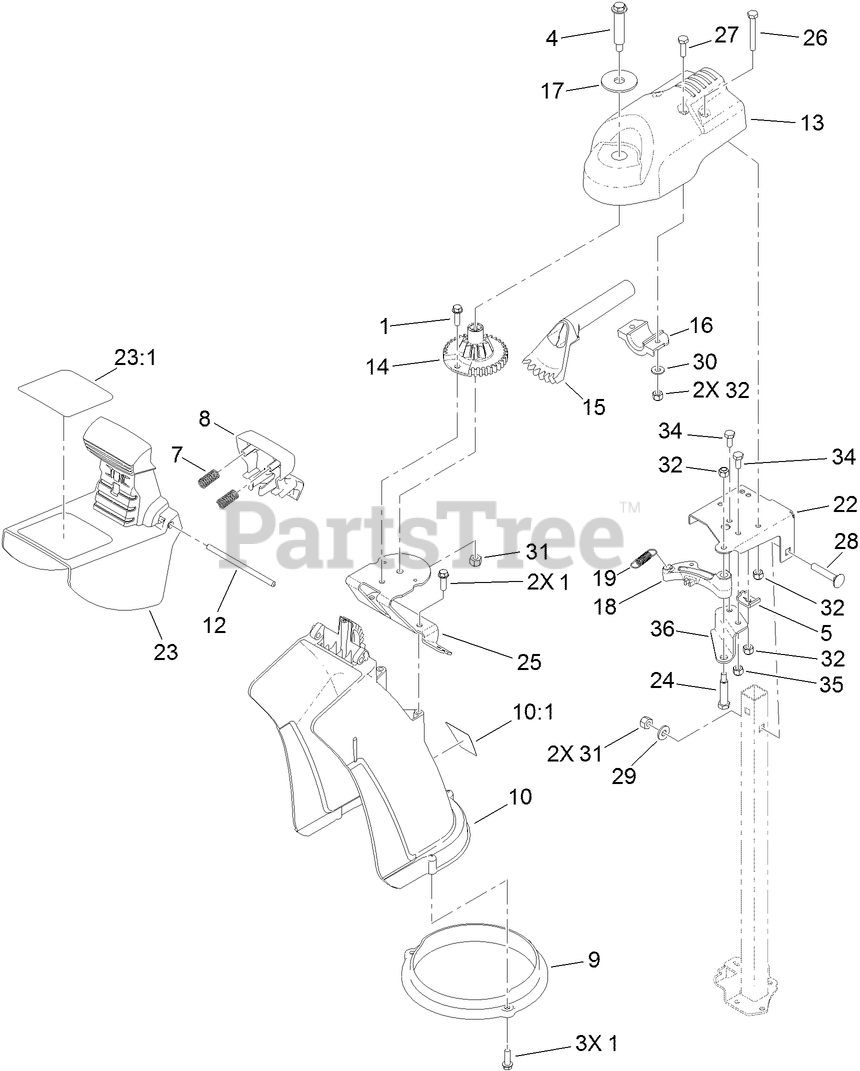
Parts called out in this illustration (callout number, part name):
1	SCREW-HWH
4	BOLT-SHOULDER
5	CLAMP-CABLE
8	TRIGGER-DEFLECTOR
9	RING-CHUTE
10:1	DECAL-GUARANTEE
13	MOUNT-CHUTE, DISCHARGE
14	GEAR-CHUTE
15	GEAR-BEVEL
16	MOUNT-GEAR, BEVEL
17	WASHER-FLAT
18	LATCH-CHUTE
19	SPRING-LATCH, CHUTE
22	BRACKET-SUPPORT, CHUTE
23	DEFLECTOR-CHUTE
23:1	DECAL-DANGER
24	BOLT-SHOULDER
25	BRACKET-MOUNT, CHUTE
26	SCREW-HH
27	SCREW-HH
28	BOLT-CAR
29	WASHER-FLAT
30	WASHER-FLAT
31	NUT-LOCK, NI
32	NUT-LOCK, NI
34	SCREW-HH
35	NUT-LOCK, NI
36	BRACKET-SUPPORT, LATCH
